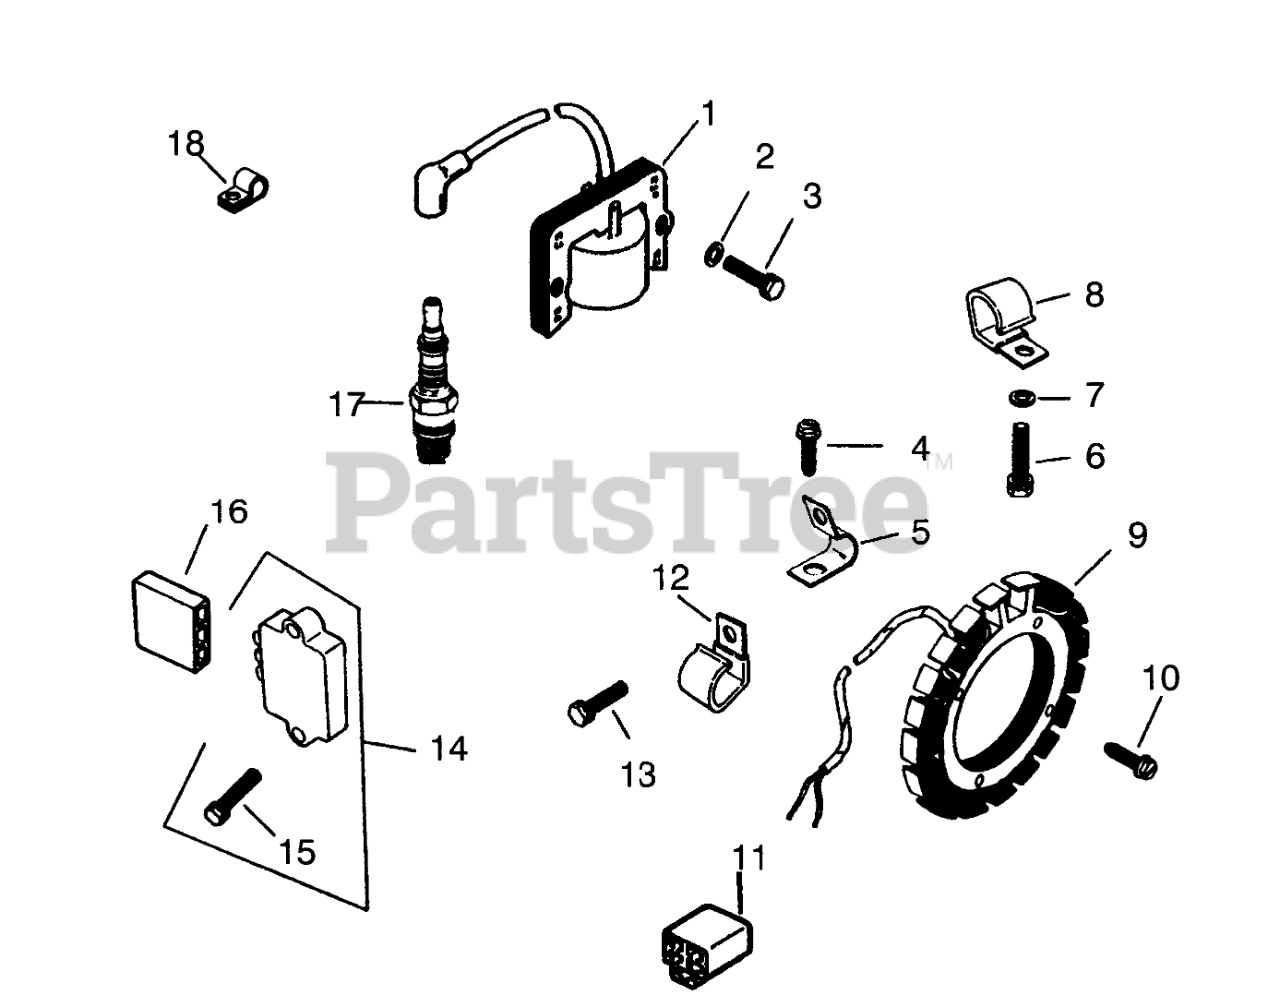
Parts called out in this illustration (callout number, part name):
1	Module-Ignition
2	Washer
3	Screw
4	Screw-Hex. Hd.
6	Screw
7	Washer
8	Clip
9	Kit-Stator 15 am (Incl. Ref. #8)
10	Screw
11	Connector
12	CLIP
13	SCREW-HH
14	Regulator-Rectifier
15	Screw
16	Connector
17	Plug-Spark
18	Clip-Hi-Tension
